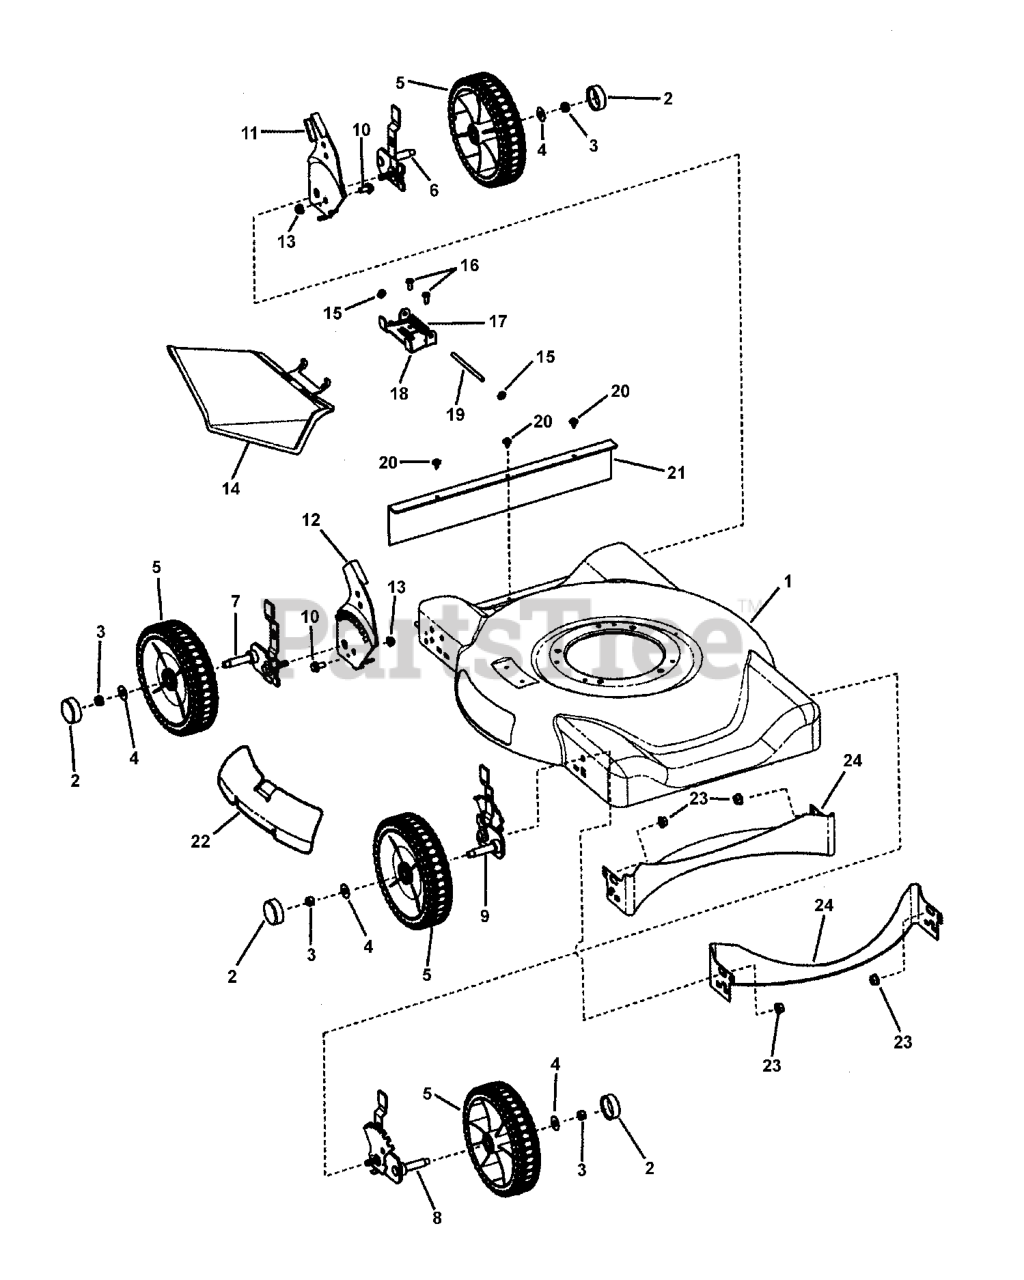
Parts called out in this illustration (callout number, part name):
1	DECK, 22" WBM, Side Discharge
2	HUBCAP, Round, Black
3	NUT, 3/8-16 Hex Center Lock, YZ
4	WASHER, 1" O.D. x .387 I.D. Flat
5	ASSY, Wheel, 8"x 2" Idle, Murray Tread, BB, Gray
6	ASSY, Height-of-Cut, Left Rear, 22" WBM, Low Cost
7	ASSY, Height-of-Cut, Right Rear, 22" WBM, Low Cost
8	ASSY, Height-of-Cut, Left Front, 7 Position
9	ASSY, Height-of-Cut, Right Front, 7 Position
10	BOLT, 5/16-18 x 5/8" Hex Flange Lock, YZ
11	BRACKET Lower Handle, LH Low Cost
12	BRACKET Lower Handle, RH Low Cost
13	NUT, 5/16-18 Flange Lock, YZ
14	CHUTE, Plastic S/D
15	PUSHNUT, 1/4"
16	SCREW, 1/4-20 x 11/16" Pan Head Self-Tap - Torx
17	SPRING, Torsion, Chute
18	BRACKET, Chute Low Cost
19	ROD, Pivot, Mulch Cover
20	SCREW, #10-24 x 1/2" Hex Washer Self-Tap - Sems
21	GUARD, Rear
22	PLATE, Mulch
23	NUT, 3/8-16 Hex Flange Lock, GR 5
24	BAFFLE, 22" Side Discharge
